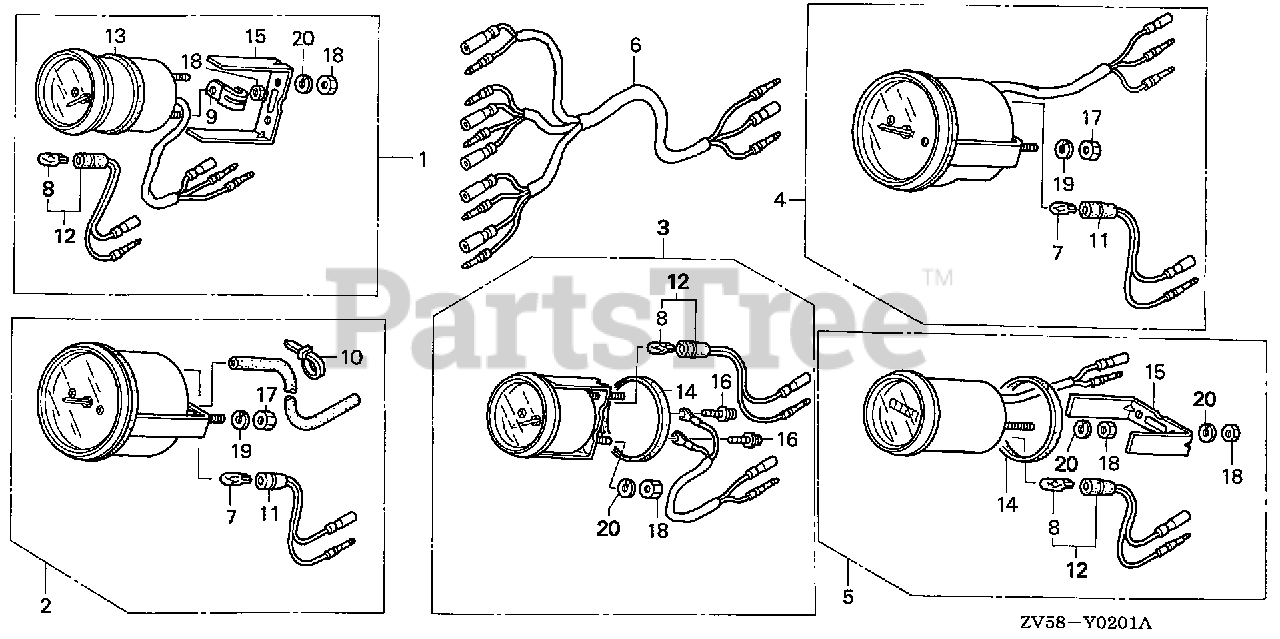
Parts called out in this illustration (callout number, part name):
1	METER KIT, TRIM (WHITE)
1	METER KIT, TRIM
1	METER KIT, TRIM *NHA85* (B) (BLACK)
2	SPEEDOMETER KIT (WHITE) (NOT AVAILABLE)
2	METER KIT, SPEED *NH1D* (B) (BLACK)
3	METER KIT, VOLT (WHITE)
3	METER KIT, VOLT *NHA85* (B) (BLACK)
4	METER KIT, TACHO (WHITE) (NOT AVAILABLE)
4	METER KIT, TACHO *NHA85* (B) (BLACK)
5	METER KIT, HOUR (WHITE) (NA USE ALT:39700-ZW5-000ZA)
5	METER KIT, HOUR (B) (NA USE ALT:39700-ZW5-000ZA)
6	HARNESS ASSY., METER (B)
7	BULB, WEDGE BASE (T10) (12V 1.7W) (STANLEY)
8	BULB, WEDGE BASE (12V1.7W) (TOSHIBA)
9	CLAMP
10	BAND, SELF-LOCK
11	SOCKET
12	SOCKET
13	GASKET (TO 1015209) (FROM 1015210)
14	GASKET
15	BRACKET (TO 1015209) (FROM 1015210)
16	SCREW-WASHER (3X22)
17	NUT, HEX. (5MM)
18	NUT, HEX. (4MM)
19	WASHER, SPRING (5MM)
20	WASHER, SPRING (4MM)
